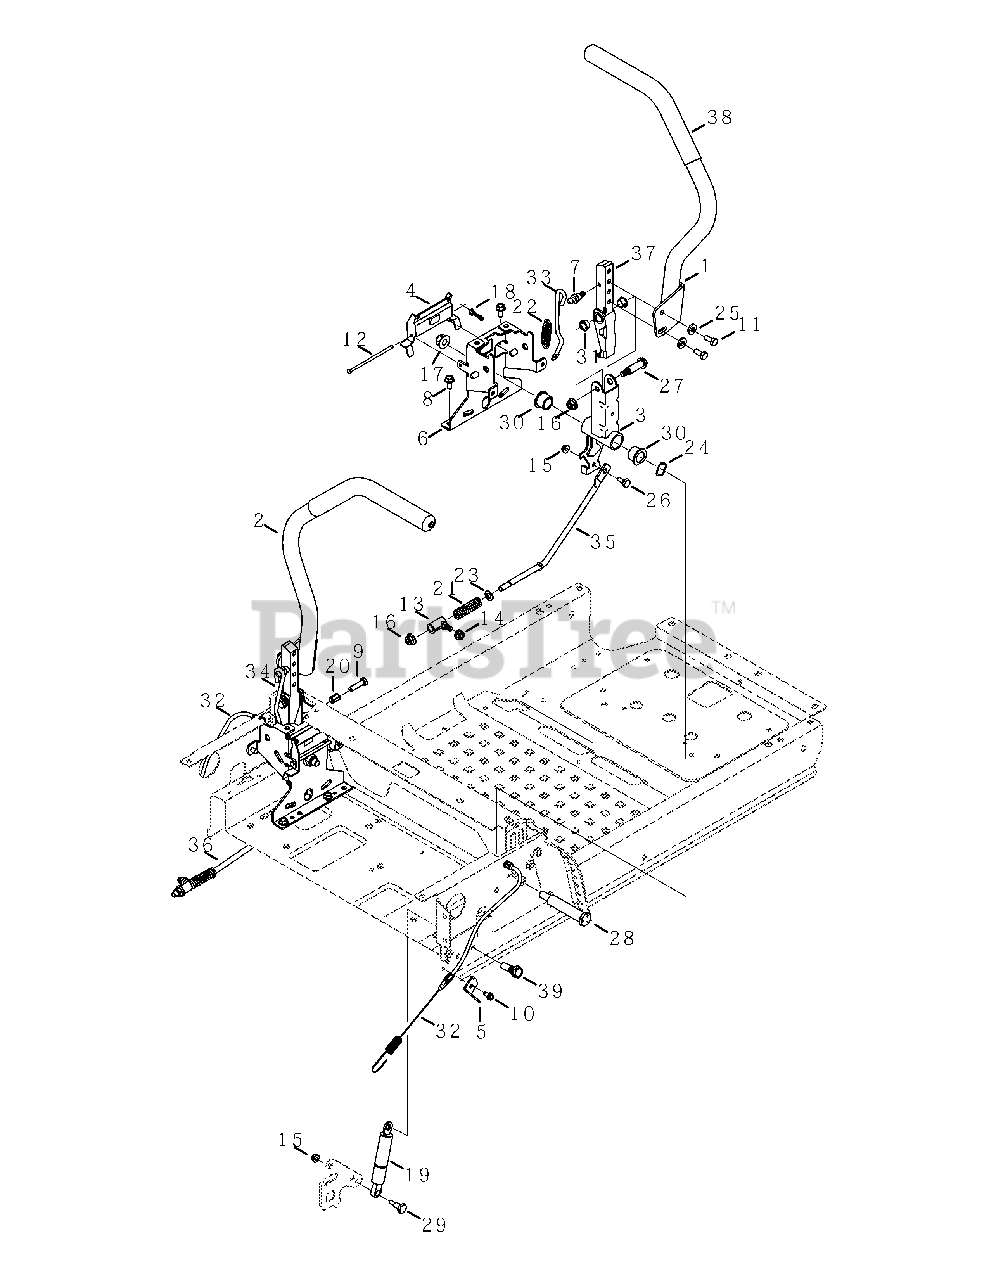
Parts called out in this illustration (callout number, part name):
1	RH Lapbar Lever Assembly
2	LH Labpar Lever Assembly
3	Lapbar Pivot Bracket
4	Brake Lever Actuator
5	Brake Cable Bracket
6	Lapbar Pivot Support Bracket
7	Screw, Shoulder Ball, 5/16-18 x .48
8	Hex Washer Screw, 5/16-18 x .750
9	Hex Cap Screw, 5/16-18 x 1.25
10	Hex Washer Screw, 1/4-20 x .500
11	Hex Head Screw, 5/16-18 x .75 Patch
12	Pin, .188 x 4.1
13	Ferrule, 3/8 ID x .420 Shldr
14	Flange Lock Nut, 5/16-18
15	Flange Lock Nut, 1/4-20
16	Flange Lock Nut, 3/8-16
17	Flange Lock Nut, 1/2-13
18	Bow-Tie Cotter Pin
19	Dampener, .87 OD x 7.06 Lg
20	Nut, 5/16-18
21	Compression Spring, .45 x 3.215
22	Extension Spring, .56 x 2.31 x .105
23	Flat Washer, .385 x .62 x .063
24	Washer, Wave, .785 x 1.0 x .012
25	Flat Washer, .344 x .750 x .120
26	Shoulder Screw, .375 Dia. x .181
27	Shoulder Screw, .498 Dia. x 1.296
28	Shoulder Screw, .75 x 3.25 x 1/2-13
29	Shoulder Screw, .395 Dia. x .56
30	Bearing, .75 x 1.00 x .73
31	Flange Bearing, .500 x .627
32	Park Brake Cable
33	Lapbar Detent Rod, RH
34	Lapbar Detent Rod, LH
35	Hydro Control Rod, RH
36	Hydro Control Rod, LH
37	Lower Arm
38	Lapbar Grip, Short 1.125 x 5.0 Lg
39	Shoulder Screw, .395 Dia. x .83
